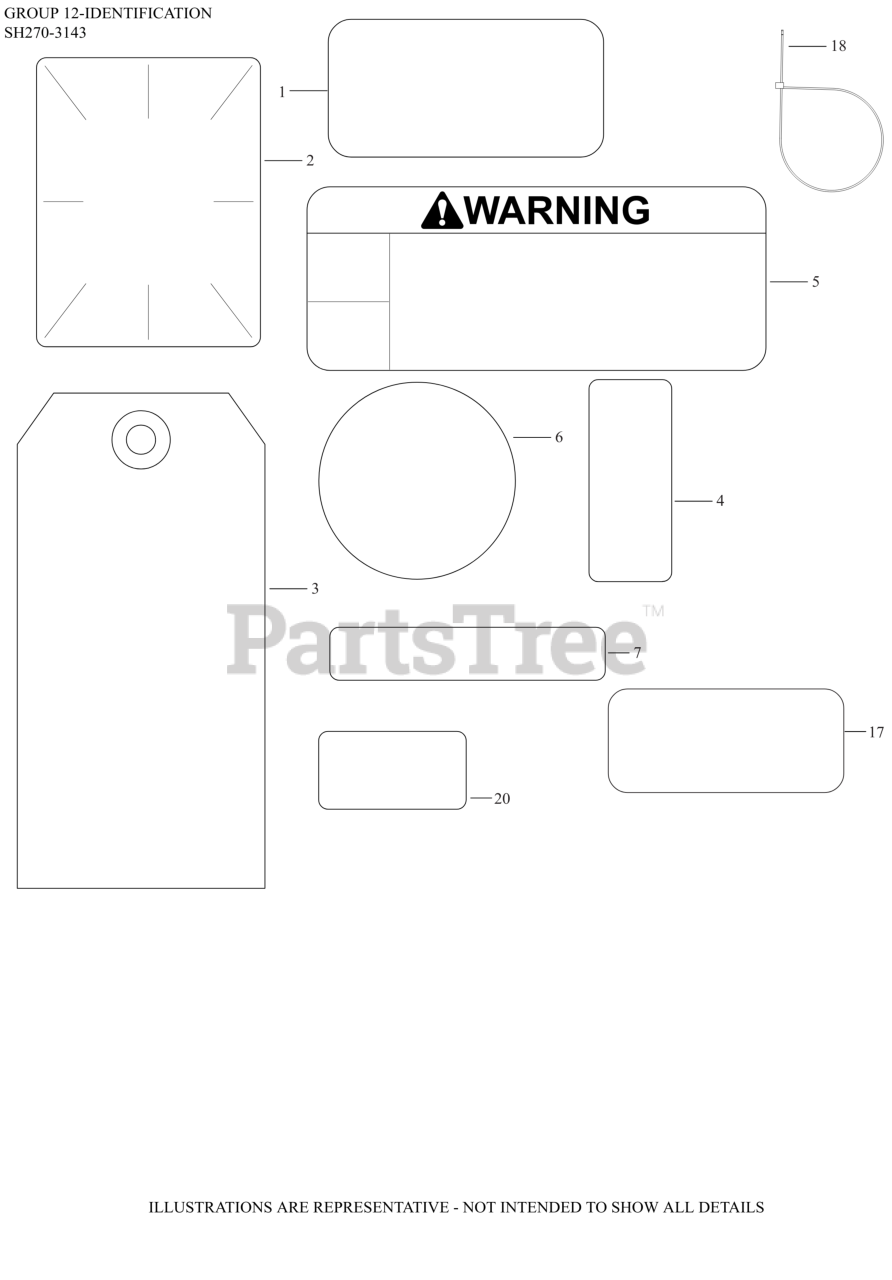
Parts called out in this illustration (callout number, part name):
1	LABEL, MAINTENANCE (CKY)
2	LABEL, CLEAR LAMINATION
3	TAG, HANG
3	TAG, PROP 65-OIL FILL ASSEMBLED
4	DECAL, FUEL/CHOKE - ON/OFF
5	DECAL, WARNING
6	LABEL, RECOIL 75MM
7	DECAL, THROTTLE
17	DECAL, ETHANOL WARNING
20	LABEL, HP SH270
